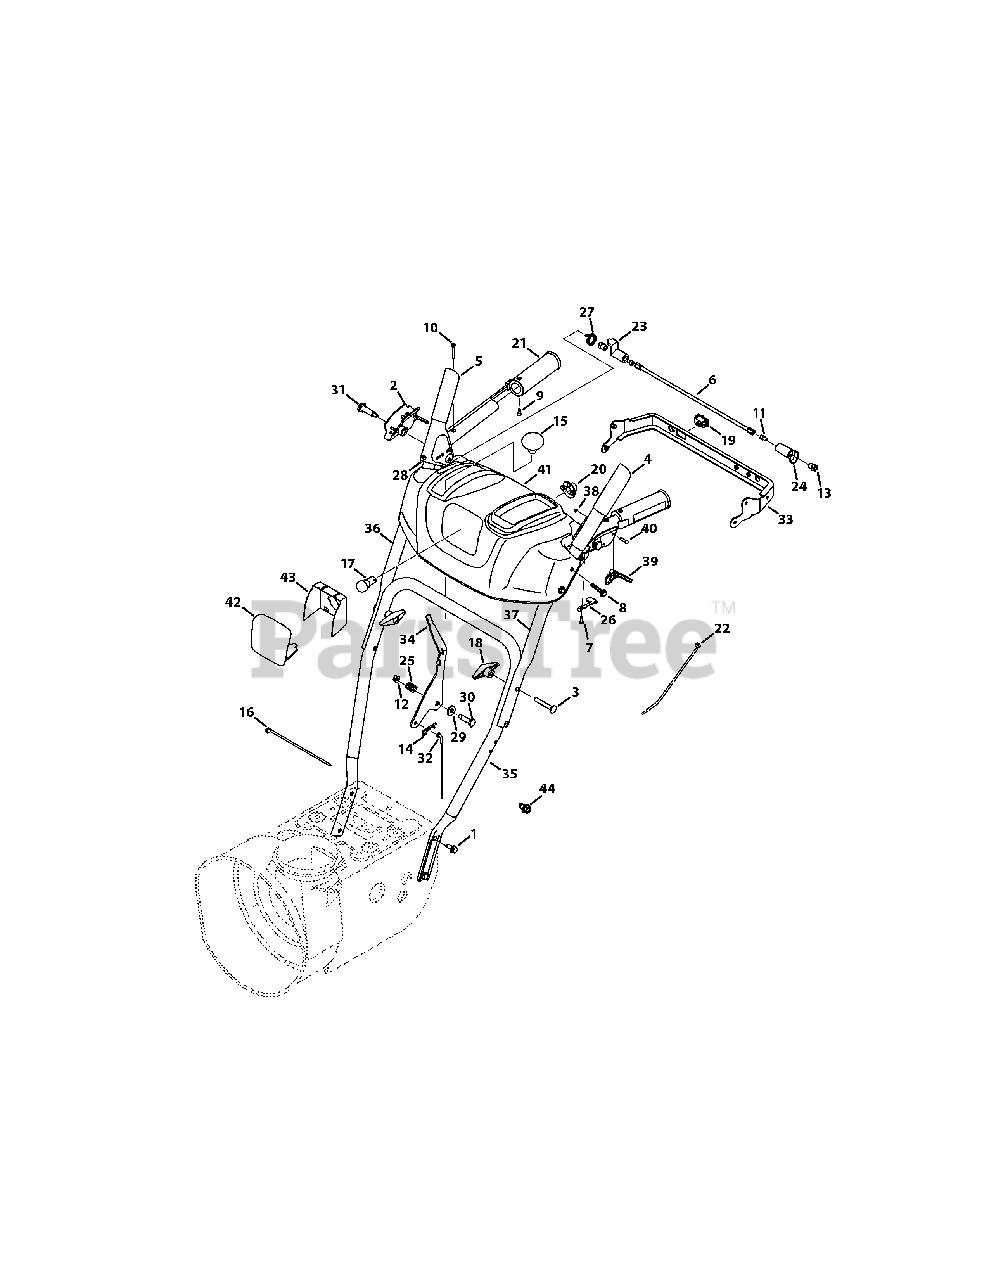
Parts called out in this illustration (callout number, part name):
1	Screw, Taptite, 5/16-18 x .750
2	Clutch Lock, RH
2	Clutch Lock, LH
3	Screw, Carriage, 5/16-18 x 2.50
4	Auger Engage, Black, LH
5	Drive Engage, Black, RH
6	Pivot Rod
7	Screw, Plastite, 8-16 x .50
8	Screw, Taptite, 1/4-20 x 1.625
9	Screw, 10-16 x 0.625
10	Screw, 10-24 x 1.375
11	Screw, 1/4-20 x .50
12	Nut, Flangelock, 1/4-20
13	Nut, Hex, 1/4-20
14	Click Pin, .092 x 1.64
15	Shift Knob
16	Cable Tie, 7"
17	Lamp
18	Star Knob, 5/16-18
19	Heated Grip Switch
20	Lamp Socket
21	Heated Grip
22	Cable Tie, Push Mount
23	Plate, Lock
24	Cam, Clutch Lock
25	Compression Spring, .39 x .60 x .88
26	Clutch Lock Spring
27	Torsion Spring, 0.8156 x .3038
28	Rubber Bumper
29	Washer, Flat, .385 x .87
30	Screw, Shield, .374 x 1.05
31	Screw, Shoulder, .437 x 1.345 x 1/4-20
32	Speed Selector Cable
33	Panel Bracket
34	Shift Lever
36	Upper RH Handle
37	Upper LH Handle
38	E-Ring
39	Steering Trigger Control
40	Steering Trigger Pin, 3/16
41	Handle Panel
42	Lens Panel
43	Lens Label
44	Screw, TT, 1/4-20 x .500
